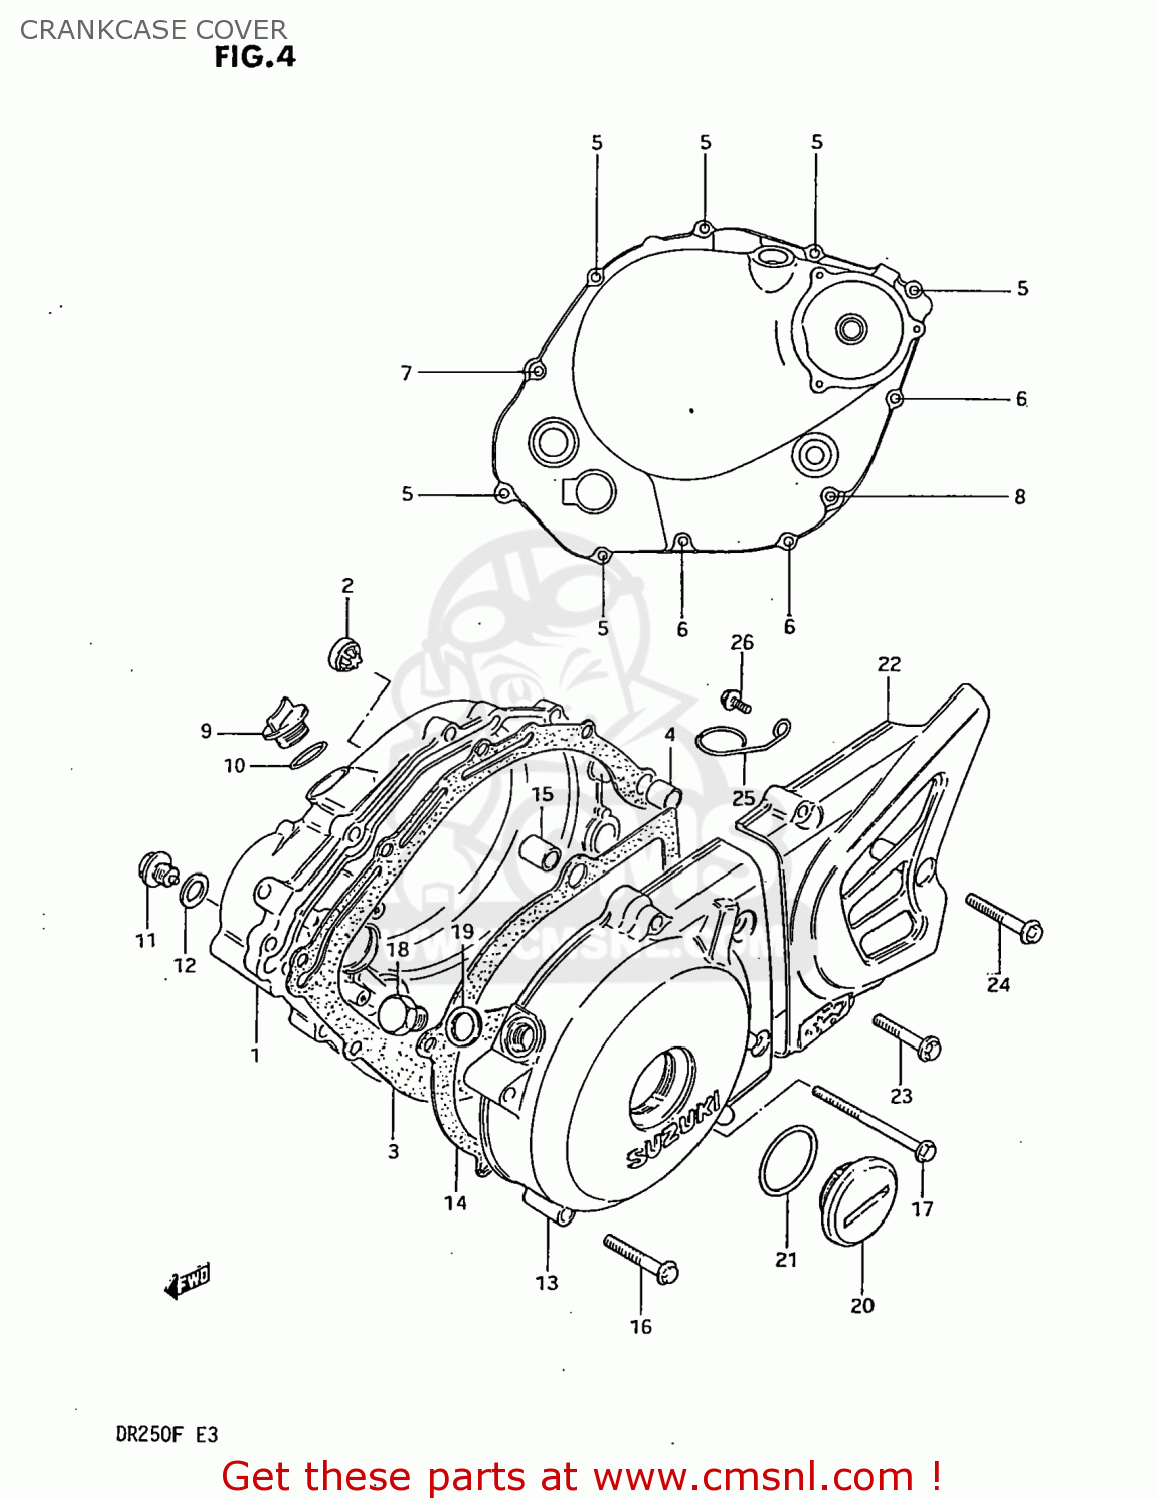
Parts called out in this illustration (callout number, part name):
1	COVER,CLUTCH
2	LENS,OIL LEVEL CHECK
3	GASKET,CLUTCH COVER (MCA)
4	PIN
5	BOLT 6X25
6	BOLT 6X35
7	BOLT 6X40
8	BOLT
9	PLUG
10	O RING(D:3.1,ID:16.8)
11	PLUG(14X12)
12	GASKET(14X19.2X2) (NAS)
13	COVER,MAGNETO
14	GASKET,MAGNETO COVER (MCA)
15	PIN
16	BOLT 6X35
17	BOLT 6X50
18	PLUG(12X9)
19	GASKET(12.1X16.2X3.7) (NAS)
20	PLUG
21	O RING(D:3.1,ID:32.7)
22	COVER,ENGINE SPROCKET
23	BOLT 5X30
24	BOLT (5X35)
25	GUIDE
26	BOLT
